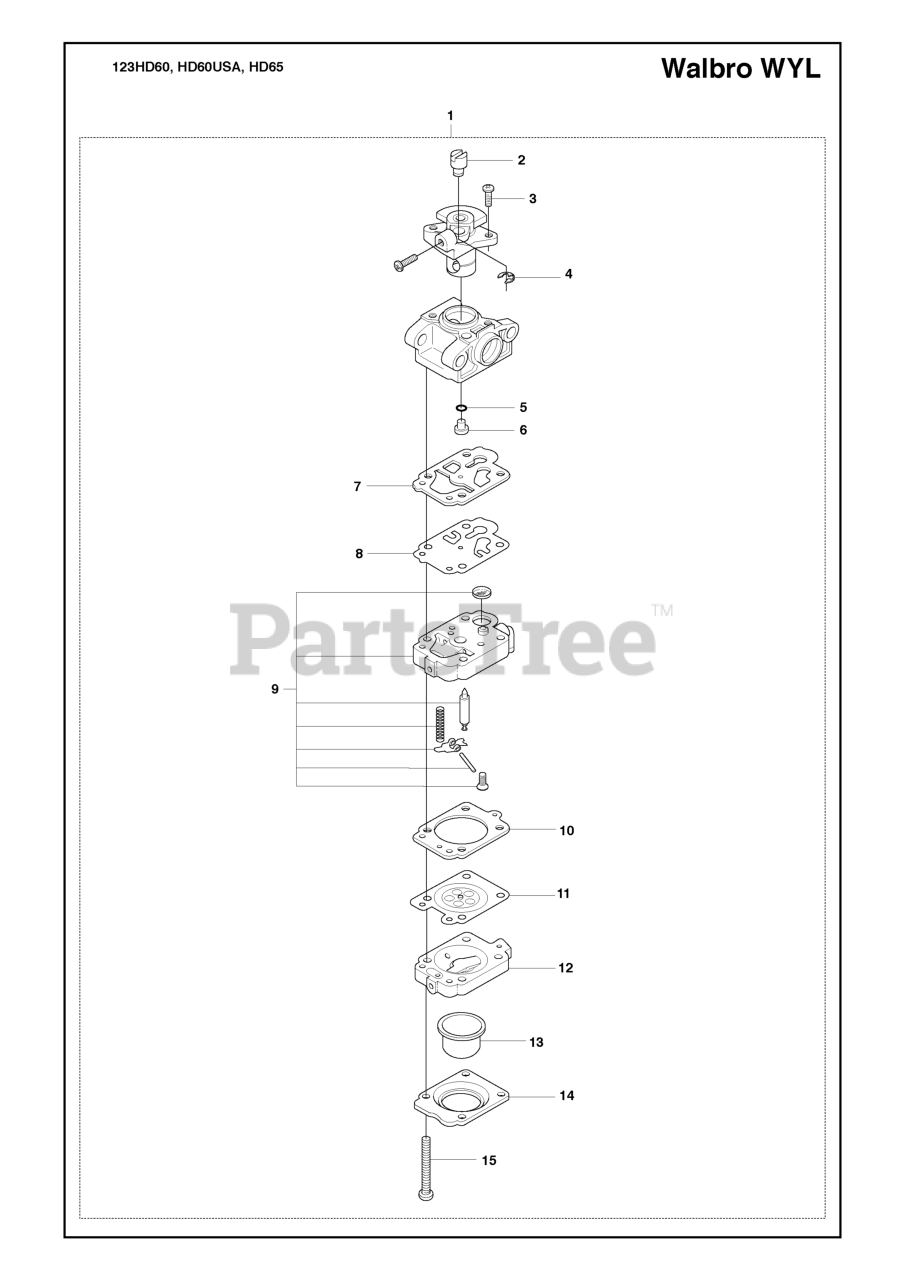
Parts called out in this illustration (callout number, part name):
1	CARBURETOR
2	CONNECTION
3	SCREW
4	RETAINING RING
7	GASKET
8	%GASKET
14	PUMP COVER
